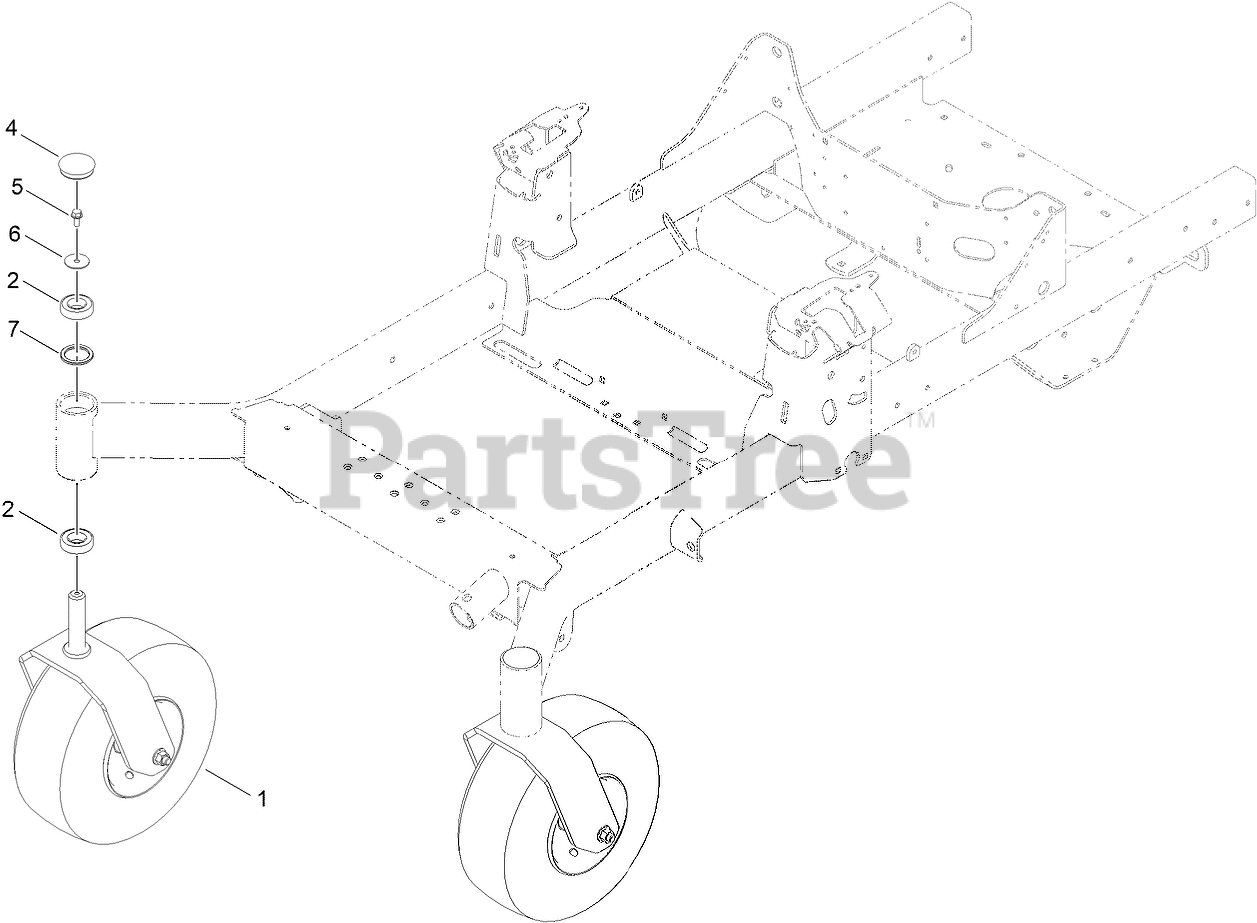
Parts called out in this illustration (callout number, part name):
1	ASM, FRONT CASTER W/ FORK
2	BEARING-BALL
4	CAP,GREASE
5	SCREW-HHF
6	WASHER-FLAT
7	SPACER-BEARING
